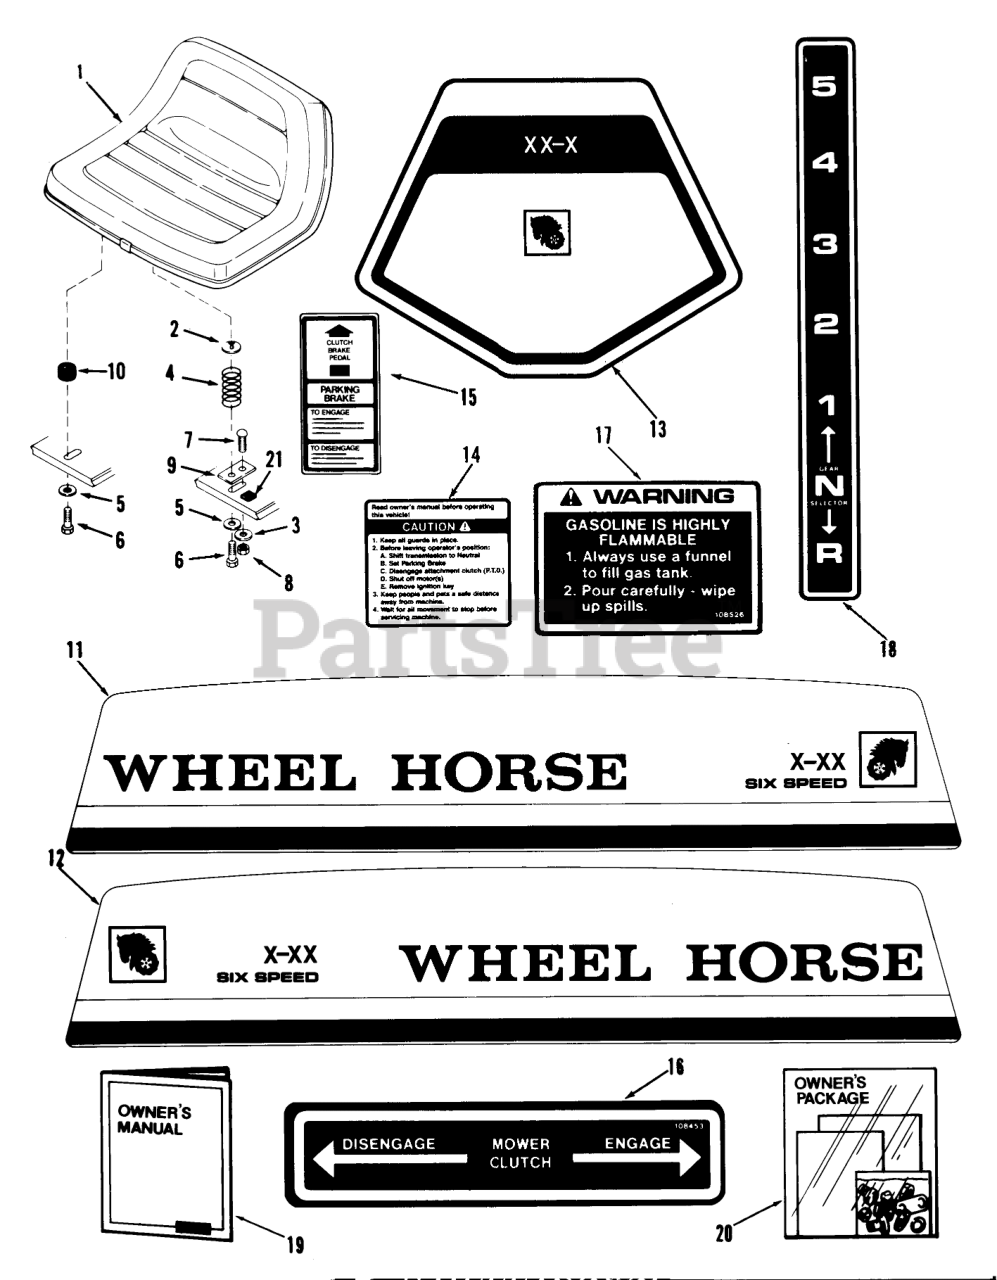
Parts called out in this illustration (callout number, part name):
5	WASHER 5/16 SAE
7	CARRIAGE BOLT -4
19	Owner-s Manual (Rider)
20	New Rider Loose Parts Pkg A-81
20	New Rider Loose Parts Pkg A-111 (23-11BP01)
20	New Rider Loose Parts Pkg A-111 (23-11BX01)
20	New Rider Loose Parts Pkg A-51
21	BUMPER
